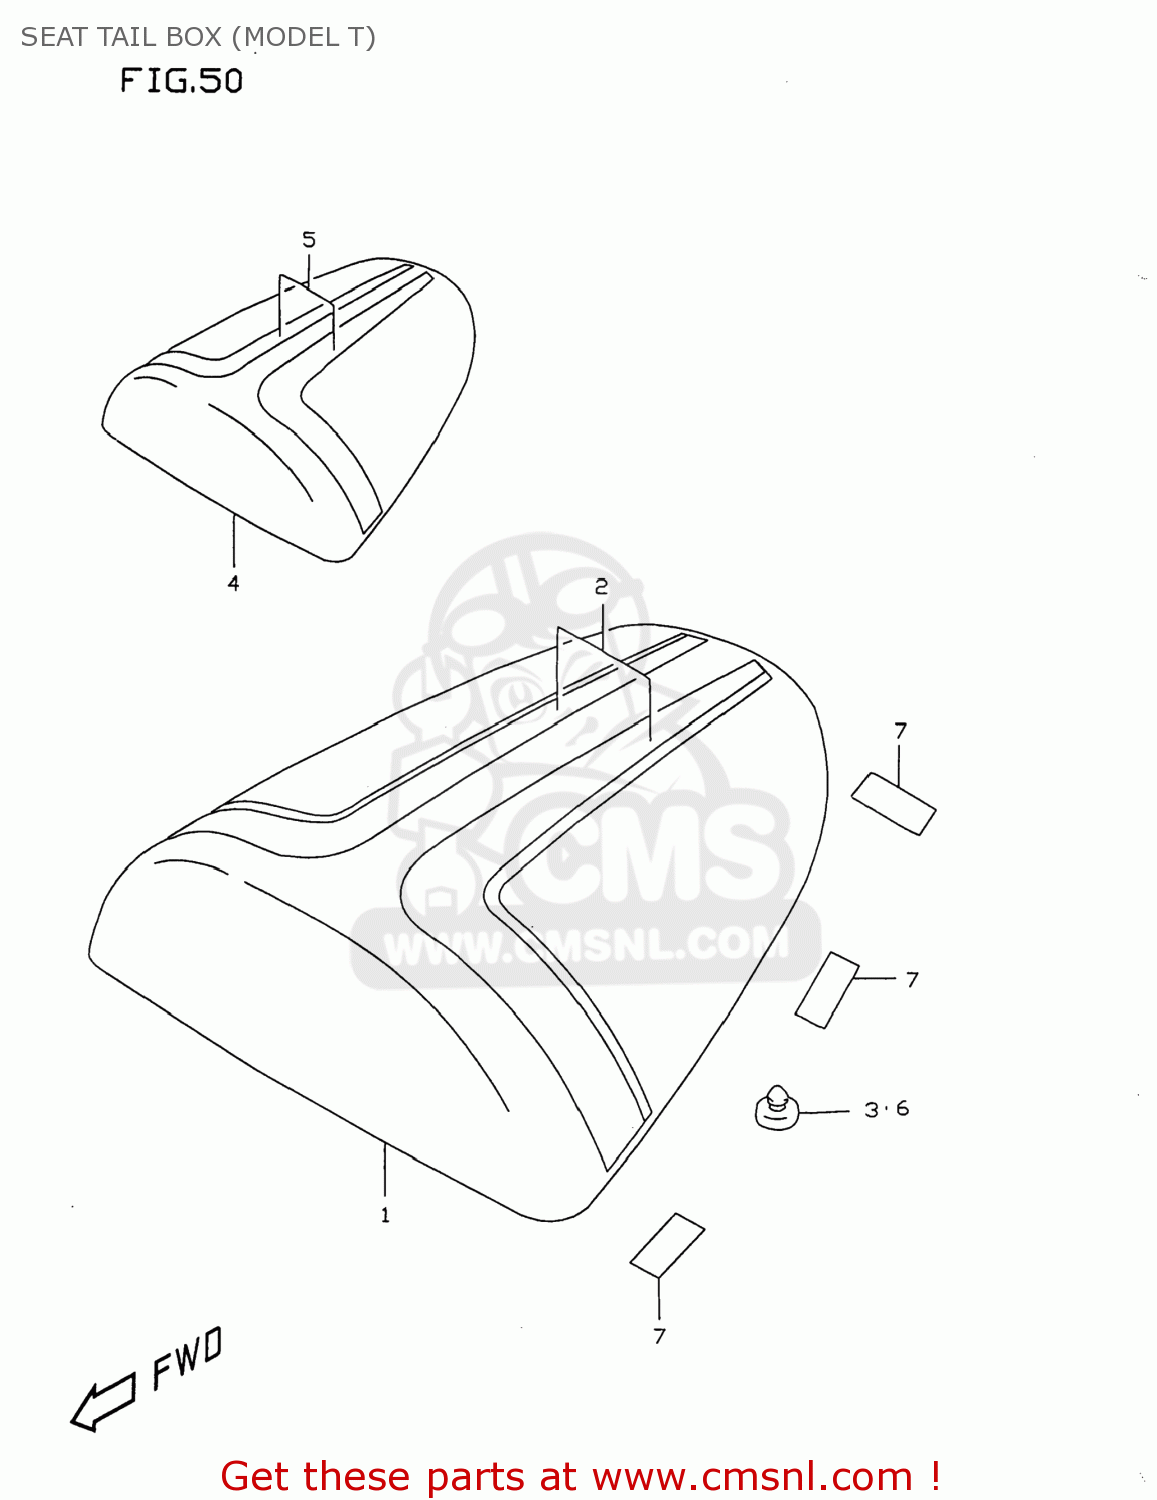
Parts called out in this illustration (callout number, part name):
1	BOX ASSY,SEAT TAIL(WHITE)
2	TAPE SET,BOX SEAT TAIL
3	CUSHION(11.5X22X20)
4	BOX ASSY,SEAT TAIL(BROWN)
5	TAPE SET,BOX SEAT TAIL(YELLOW)
6	CUSHION(11.5X22X20)
7	PROTECTOR SET,SEAT TAIL BOX
